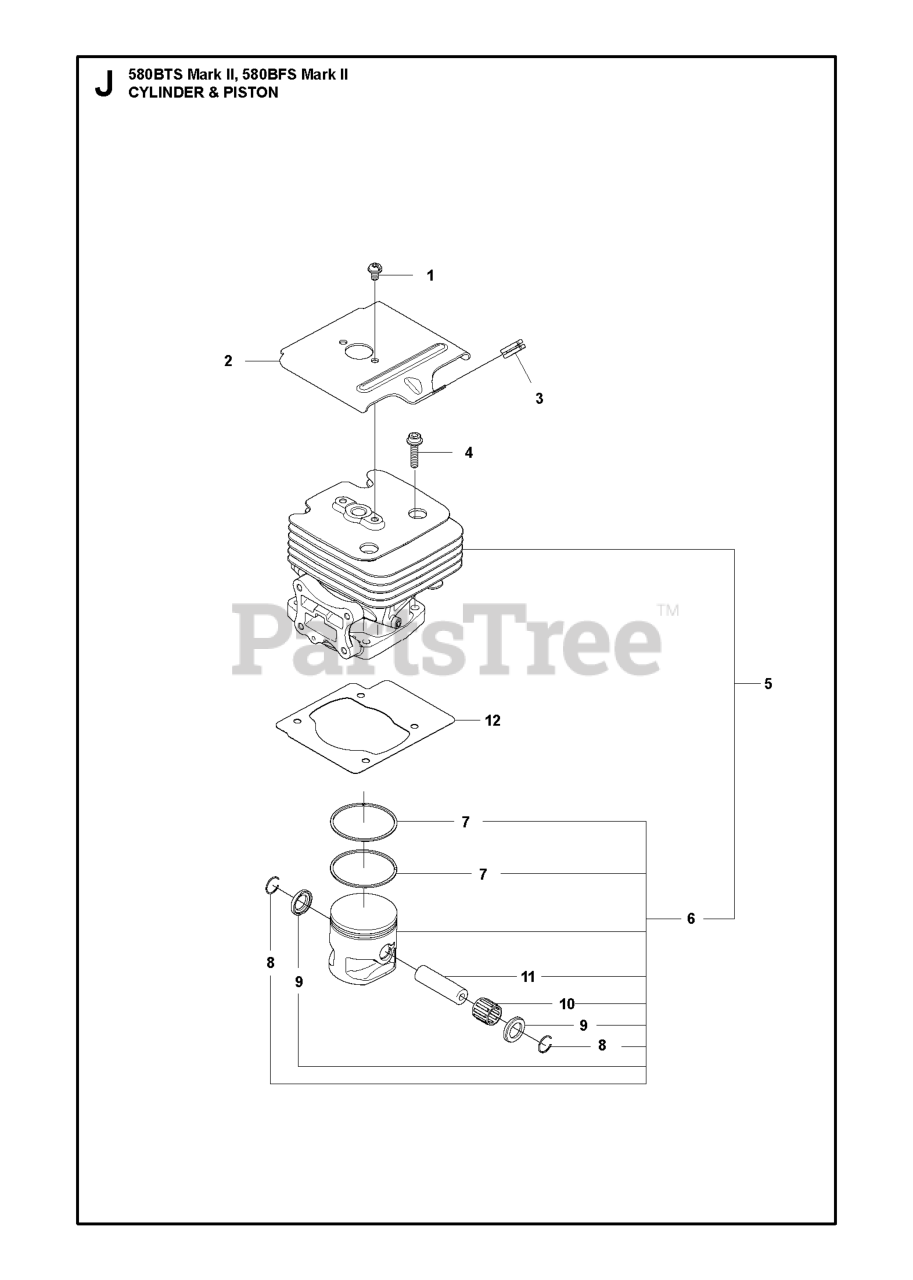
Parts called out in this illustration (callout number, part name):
5	CYLINDER ASSY
7	PISTON RING
11	PISTON PIN
